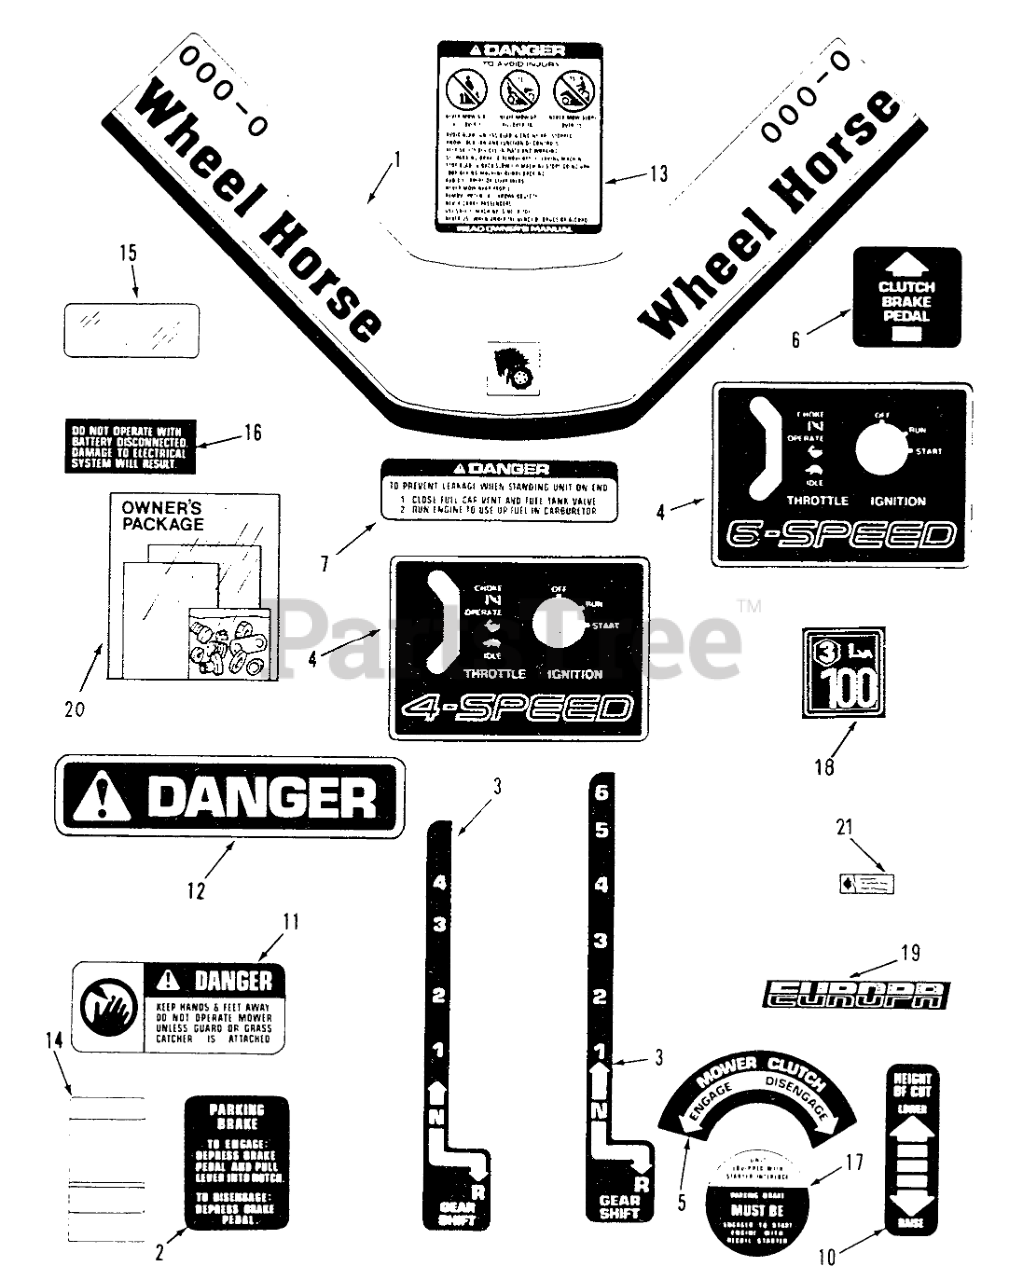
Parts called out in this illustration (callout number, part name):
1	DECAL-SHROUD
2	DECAL PARKING BRAKE
3	DECAL SHIFT 4SPD
4	DECAL 4-SPD
5	DECAL MOWER CLUTCH
6	DECAL CLUTCH & BRAKE
7	DECAL-DANGER
10	DECAL-HOC
11	Danger Decal
12	Danger Decal
13	DECAL-DANGER
14	MAINTENANCE-DECAL
15	DECAL-OVERLAY
16	DECAL ELECT SYSTEM
17	DECAL-ENGINE START
18	DECAL-EUROPE
19	DECAL-EUROPA
21	DECAL-PTO BELT ADJ
